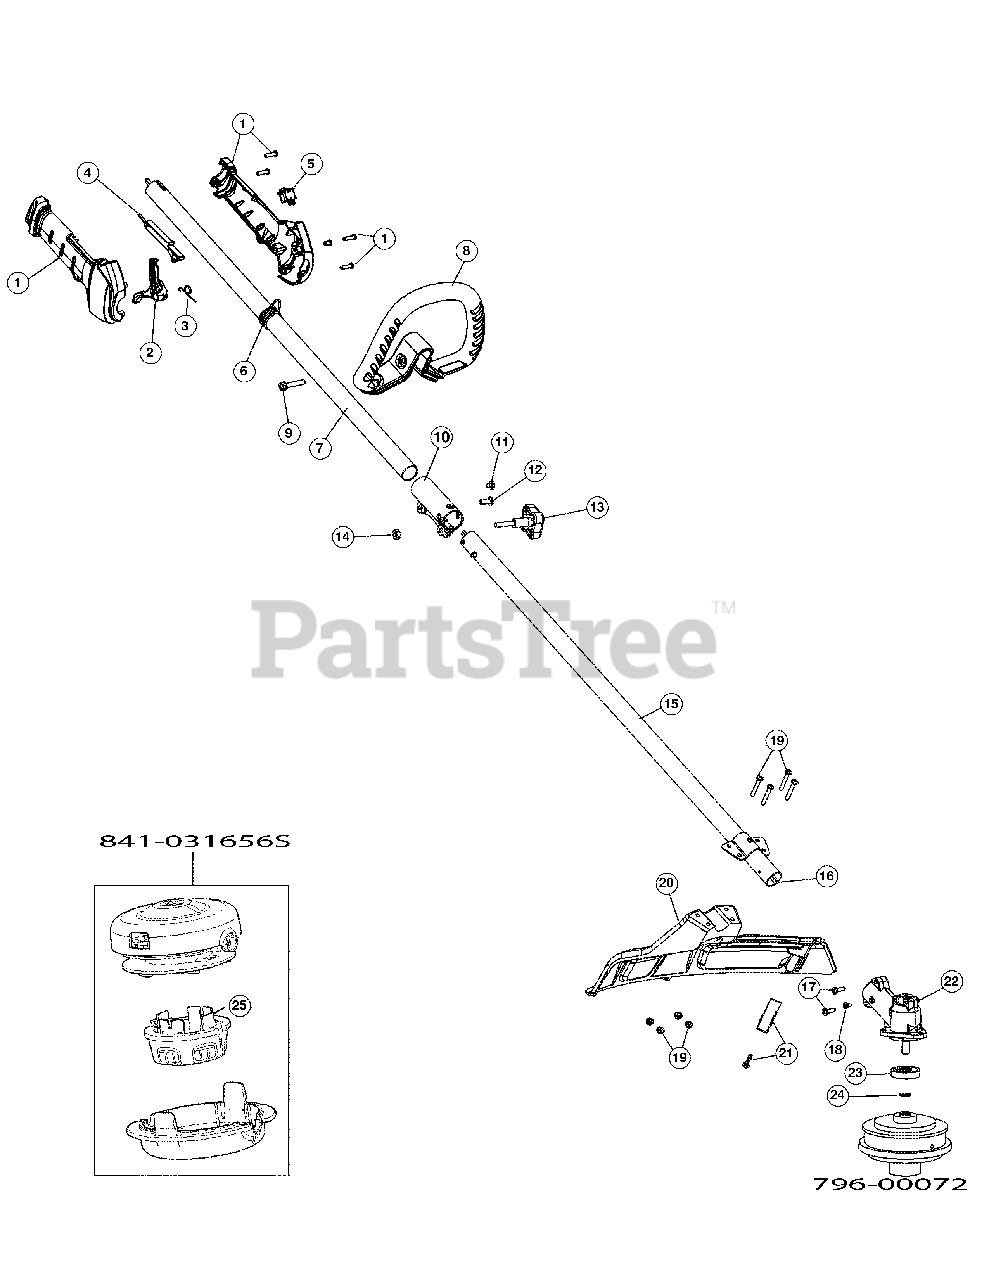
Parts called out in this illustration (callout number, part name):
1	Throttle Housing Assembly
2	Throttle Trigger
4	Throttle Lock-Out
6	Shoulder Strap Clip
7	Upper Driver Shaft Housing Assembly
8	D-Handle Assembly
10	Split Boom Coupler
11	Anti-Rotation Screw
13	Adjustment Knob
14	Knob Retaining Nut
15	Lower Drive Shaft Assembly
16	Flexible Drive Shaft
17	Lower Clamp Assembly
18	Anti-Rotation Screw
19	Shield Mounting Screw & Nut
20	Shield Assembly
21	Blade Assembly
22	Gearbox Assembly
23	Blade Driver
796-00072	Cutting Head Assembly
841-031656S	Cutting Head Assembly
